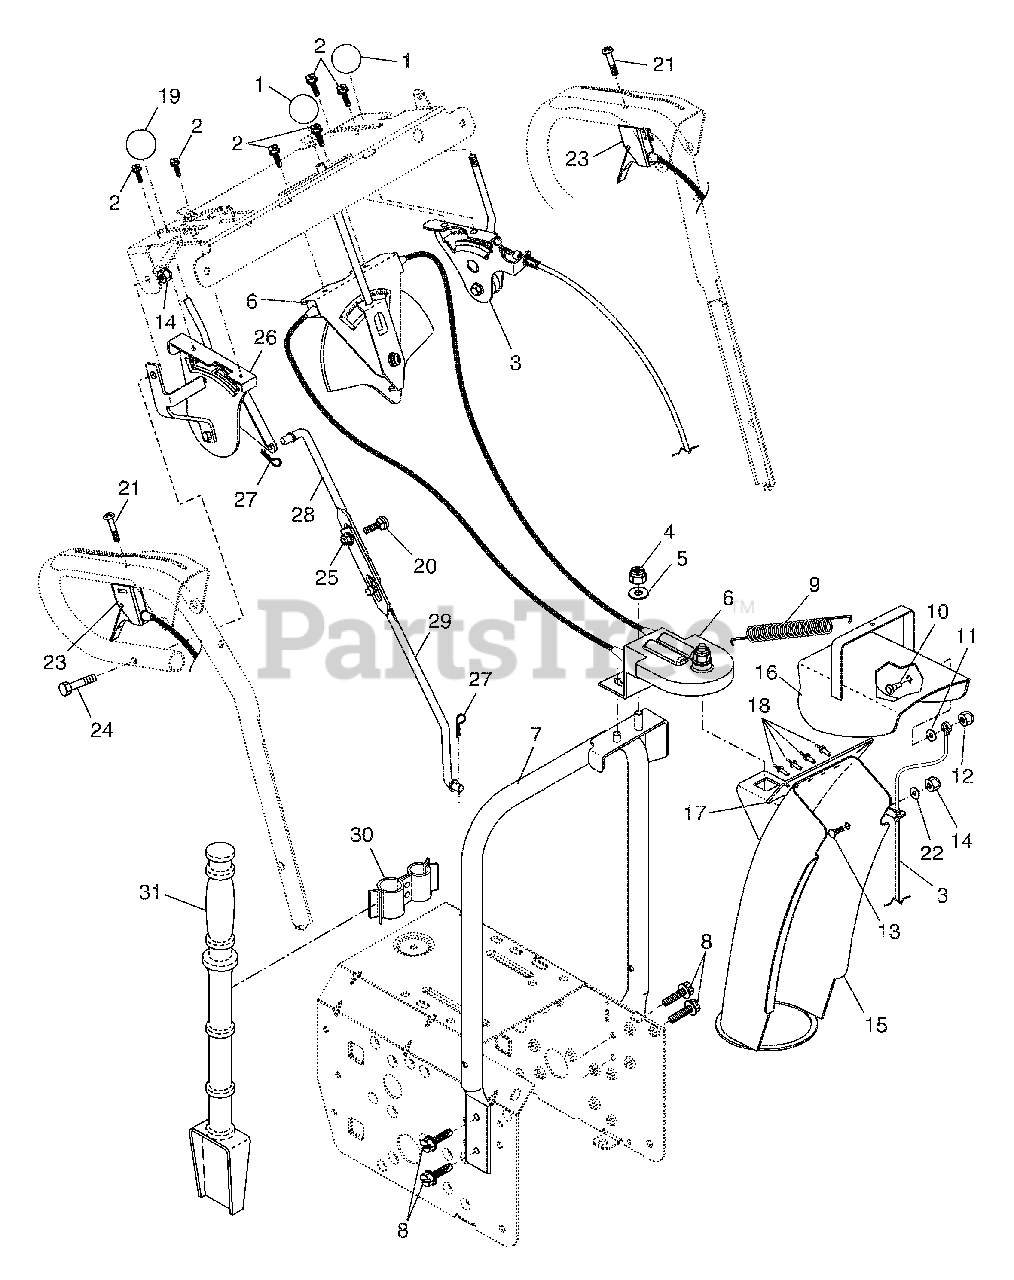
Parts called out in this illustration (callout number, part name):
1	Knob, Lever
2	Screw #10-24 x 5/8
3	Control Assembly, Deflector
4	Nut, Lock 3/8-16
5	Washer, Flat 3/8
6	Control Assembly, Chute Rotater
7	Support, Pivot
8	Screw, Hex Head 5/16-18 x 3/4
9	Spring, Deflector
10	Bolt, Shoulder
11	Washer, Friction, Nylon
12	Nut, Lock 1/4-20
13	Bolt, Carriage 5/16-18
14	Nut, Lock 5/16-18
15	Chute Assembly
16	Deflector Assembly
17	Seal, Deflector
18	Rivet, Blind
19	Knob, Speed Control Lever
20	Bolt, Carriage 5/16-18 x 3/4
21	Screw #10-24 x 1-1/2
22	Washer, Flat 5/16
23	Control Assembly, Power Steering
24	Screw, Hex Head 5/16-18 x 1-3/4
25	Nut, Lock 5/16-18
26	Lever Assembly, Speed Control
27	Retainer, Hairpin
28	Rod, Upper, Speed Control
29	Rod, Lower, Speed Control
30	Clamp, Clean-Out Tool
31	Tool, Clean-Out
